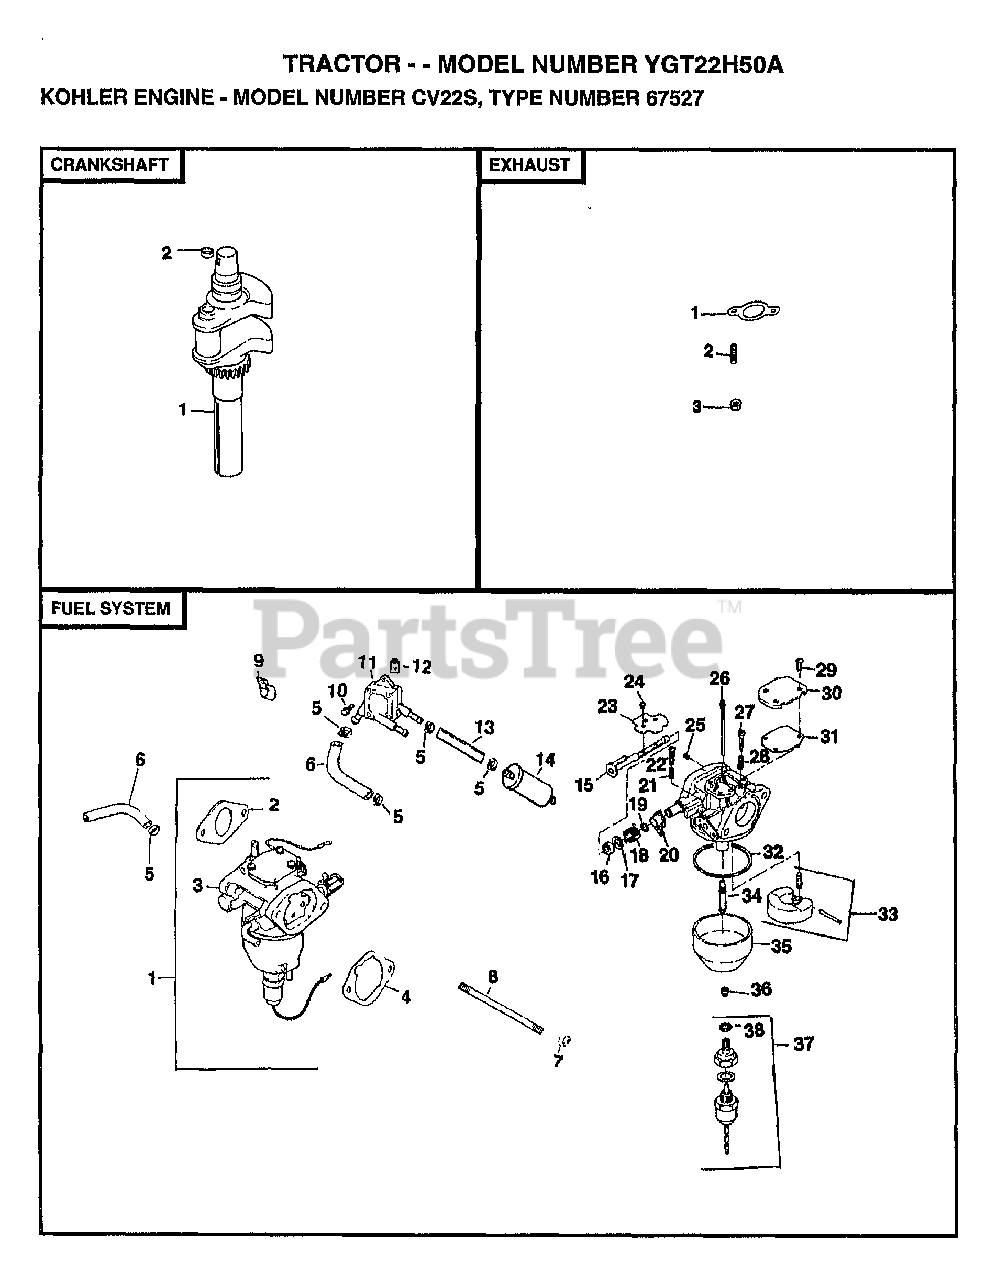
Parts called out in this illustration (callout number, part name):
1	KIT, CARBURETOR WITH GASKET
1	CRANKSHAFT
1	GASKET
2	GASKET
2	PLUG, CUP
2	STUD. EXHAUST MANIFOLD
3	CARBURETOR ASSEMBLY
3	NUT
4	GASKET
5	CLAMP, HOSE
6	LINE
7	NUT
9	CLIP, CABLE
10	SCREW
11	PUMP
12	NUT
13	LINE
14	FILTER
15	SHAFT
16	WASHER
17	COLLAR
18	SPRING
19	RING
20	LEVER
21	SPRING
22	SCREW
23	CHOKE PLATE
25	JET, AIR BLEED
26	JET, SLOW
27	SCREW
28	SPRING
29	SCREW
30	COVER
31	GASKET
32	GASKET
33	KIT, FLOAT REPAIR
34	NOZZLE, MAIN
35	CHAMBER
36	JET MAIN
37	KIT, SOLENOID VALVE
38	GASKET
